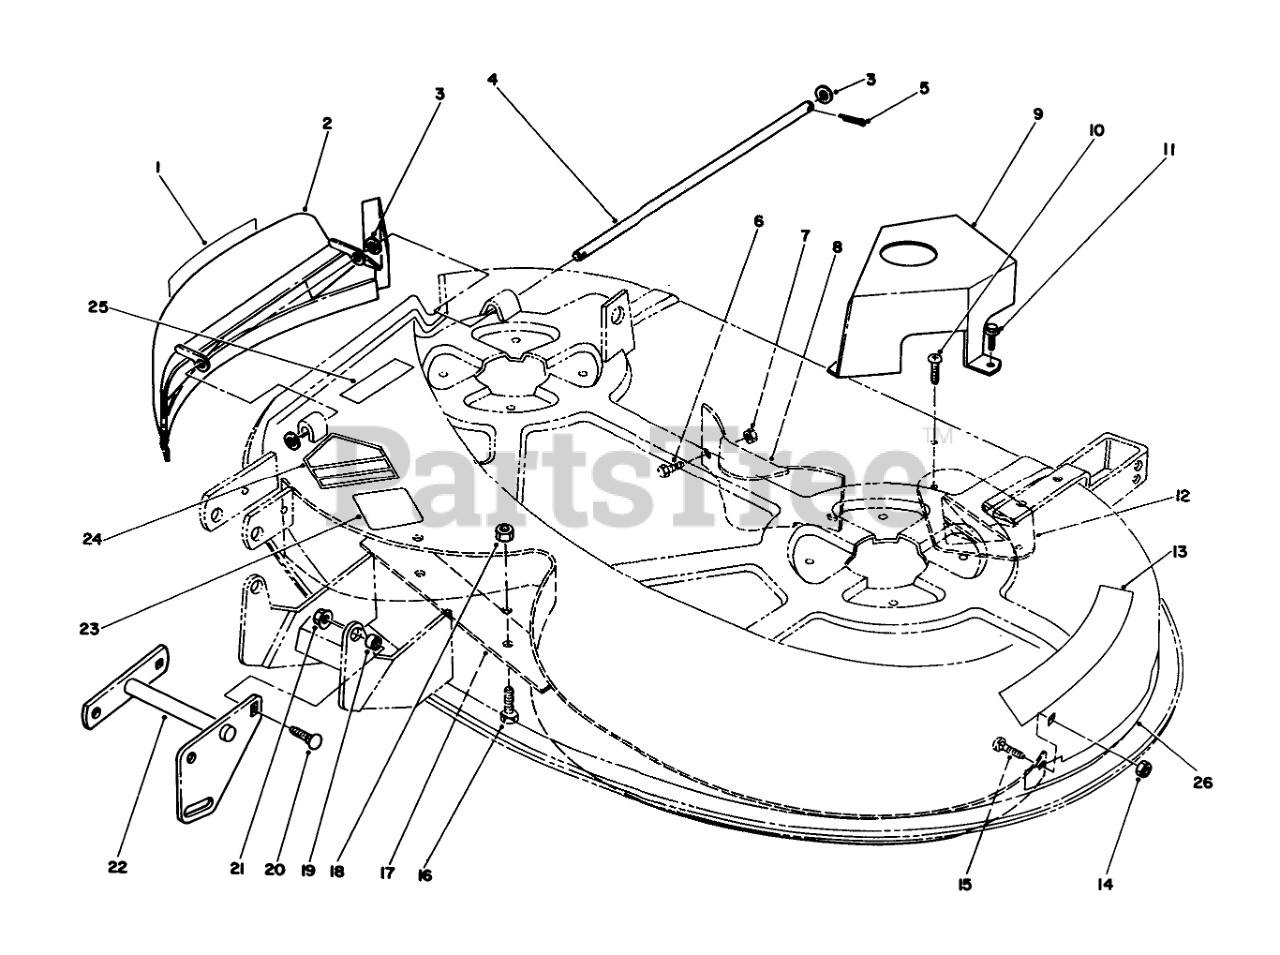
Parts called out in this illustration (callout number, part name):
1	DECAL-DANGER, THROWN OBJECT
2	Chute-Recycler
3	WASHER 5/16 SAE
5	Cotter Pin
6	H H C S
7	Nut
8	Baffle-Rear
9	COVER-BELT R
10	#8 X .625" PHILPS PAN H
11	SCREW-HWHTF
12	PLATE-KICKER
13	DECAL-DANGER
14	Nut
15	Bolt
16	Bolt
17	Baffle-38"
18	NUT
19	SPACER
20	Bolt-Carriage
21	Nut-Hex Flange Lock
22	ASM-FRONT LIFT R
23	Decal-Routing
24	DECAL-DANGER
25	DECAL-DANGER
26	DECAL-38" RECYCLER
